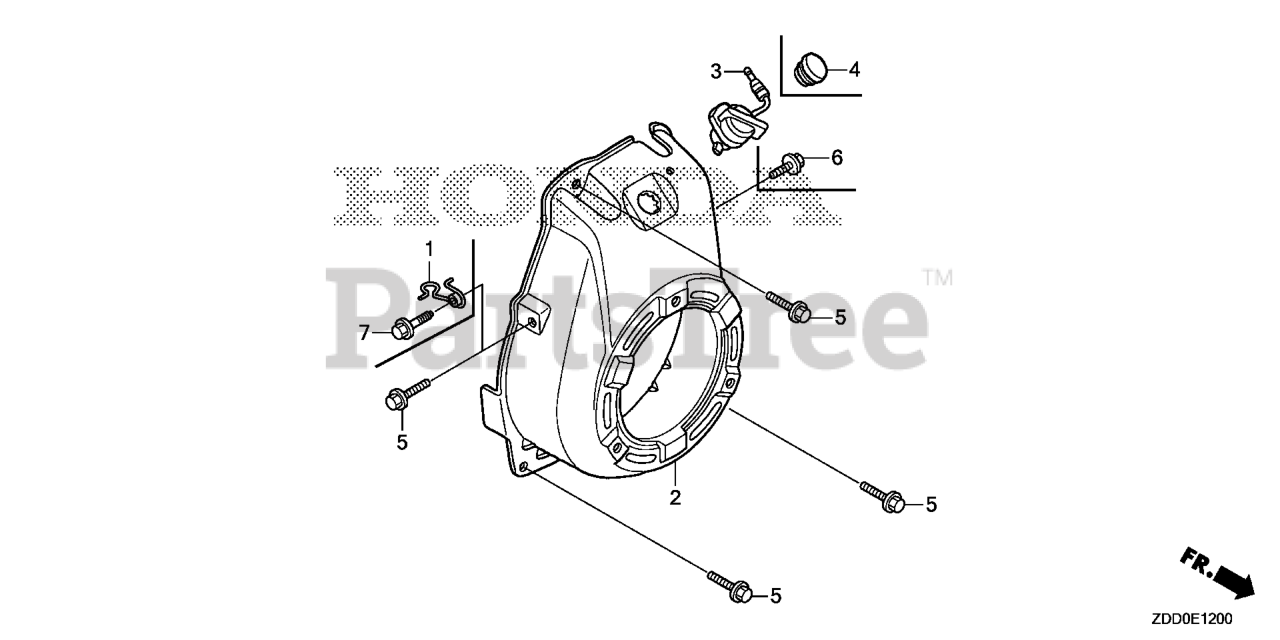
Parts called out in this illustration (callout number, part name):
2	COVER, FAN *NH1* (BLACK)
4	GROMMET, DRAIN HOLE
5	BOLT, FLANGE (6X14)
